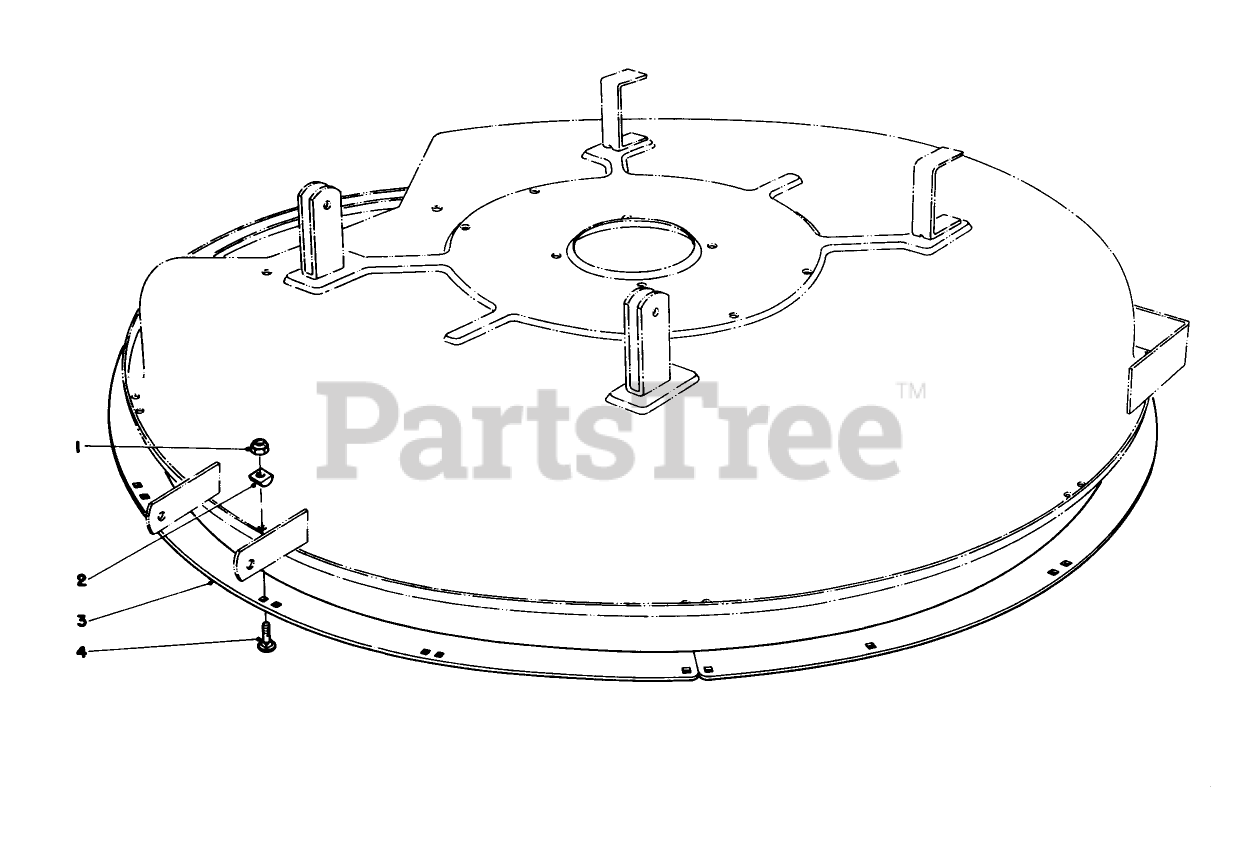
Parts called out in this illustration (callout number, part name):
1	NUT-LOCK, NI
3	DECK RING *B
4	BOLT-CARR
